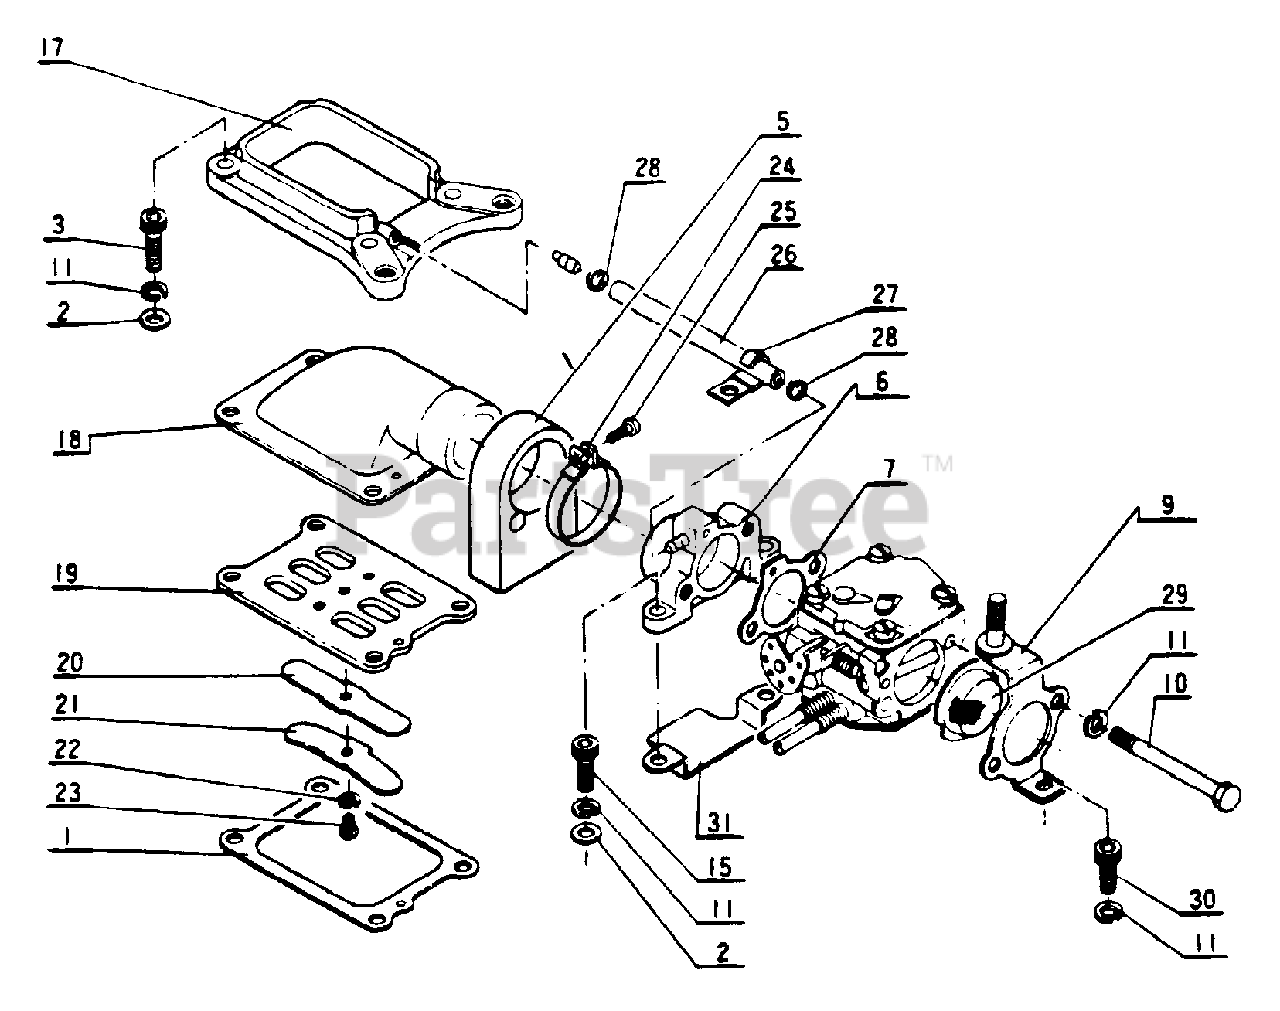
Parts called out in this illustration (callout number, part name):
1	PACKING
2	WASHER, FLAT 5.5×10×0.8
3	BOLT
5	SEAL, DUST
6	CASE, CARBURETOR
7	GASKET, INTAKE
9	PLATE, PREVENT
10	BOLT
11	WASHER, SPRING 5
15	BOLT
17	FRAME
18	PIPE, SUCTION
19	VALVE SET PLATE
20	VALVE, REED
21	GUIDE, VALVE
22	LOCKWASHER - 3
23	SCREW - 3×6
24	BAND
25	SCREW
26	CONNECTOR
27	PIPE SET CLIP
29	SCREEN
30	BOLT
31	DUST SEAL PLATE
